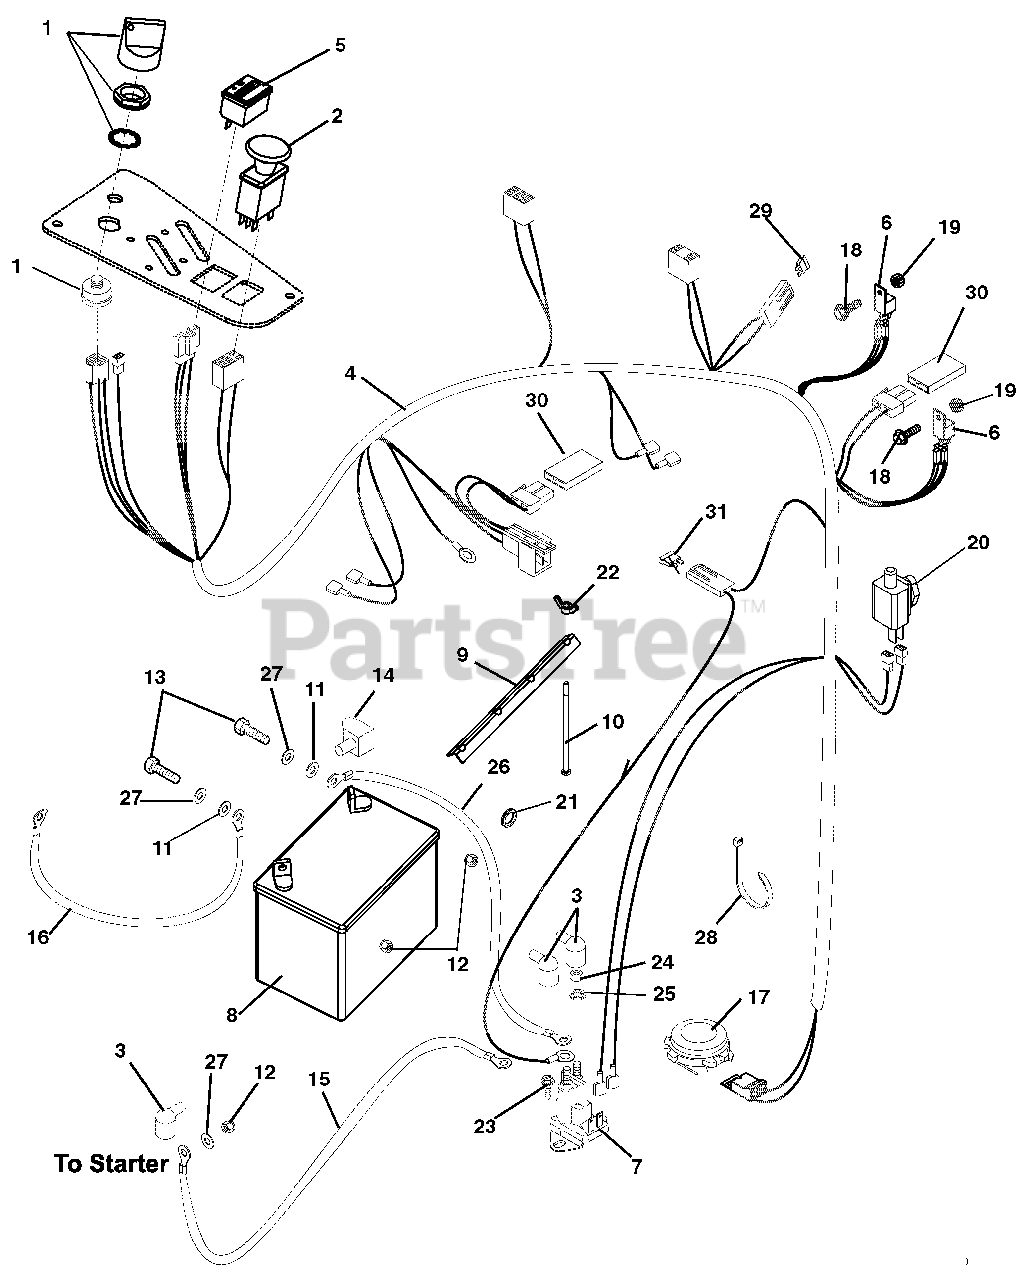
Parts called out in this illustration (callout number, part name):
1	Key Switch
2	Switch, Clutch
3	Boot, Eyelet Terminal
4	Harness- CZ Remote SOL.
5	Hour Meter – Digital
6	Relay, Sealed W/Diode
7	Solenoid
9	Hold Down
10	Bolt, Round Head Square Neck .25-20 x 7.50
11	Washer, Flat Steel .281 x .620 x .065
12	Nut, Hex .25-20
13	Bolt, Hex .25-20 x .75 Grade 5
14	Insulator
15	Cable, Positive Battery 9.00"
16	Cable, Negative Battery
17	Switch, Seat
18	Screw, Machine 10-24 x .50 Hex Washer Head
19	Nut, Locking Nylon 10-24 With Insert
20	Switch, Single Pole (N.O.)
21	Grommet, 2.12"ID .12"Groove Width, 2.50"Groove Diameter
22	Nut, Locking Wing .25-20
23	Screw, Tapping .25-20 x .50 Hex Washer Head
24	Nut, Jam .31-24
25	Washer, Locking .31 x .078 Regular
26	Cable, Starter
27	Washer, Lock .25 x .062
28	Tie, Cable LG 5.50
29	Fuse 20AMP
30	Diode, Connector Shell
31	Fuse-25 AMP
